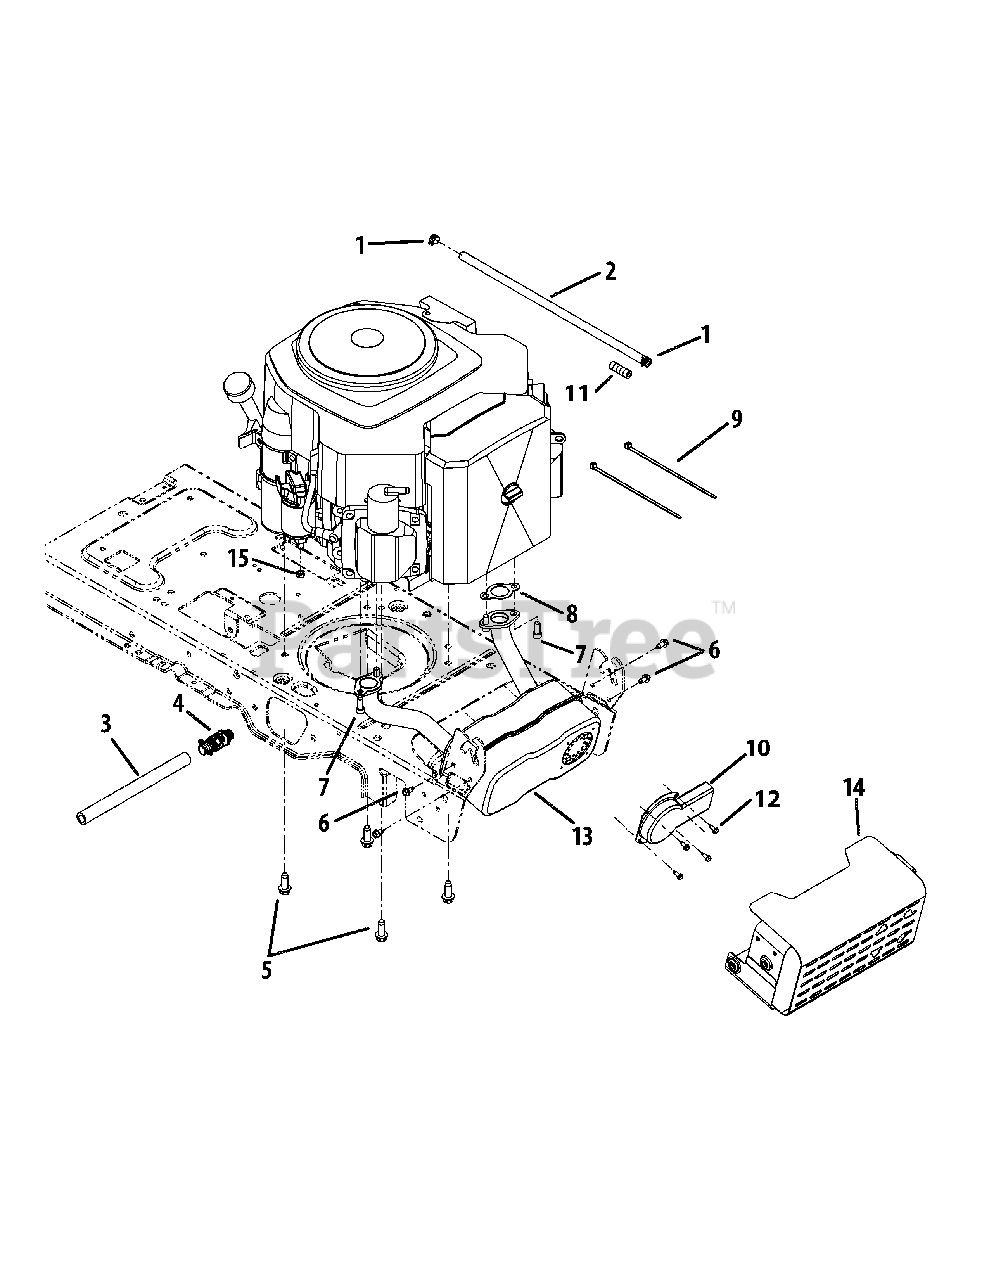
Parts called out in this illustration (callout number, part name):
1	Hose Clamp
2	Fuel Line
3	Oil Drain Hose
4	Oil Drain
5	Screw 3/8 x 1.00
6	Washer 1/4-20 x .50
7	Screw 5/16-18 x .75
8	Exhaust Gasket
9	Cable Tie
10	Long Muffler Deflector
11	Vent Hose
12	Screw 8-18 x .50
13	Muffler
14	Muffler Shield Assembly
15	Sems Nut 1/4-20
